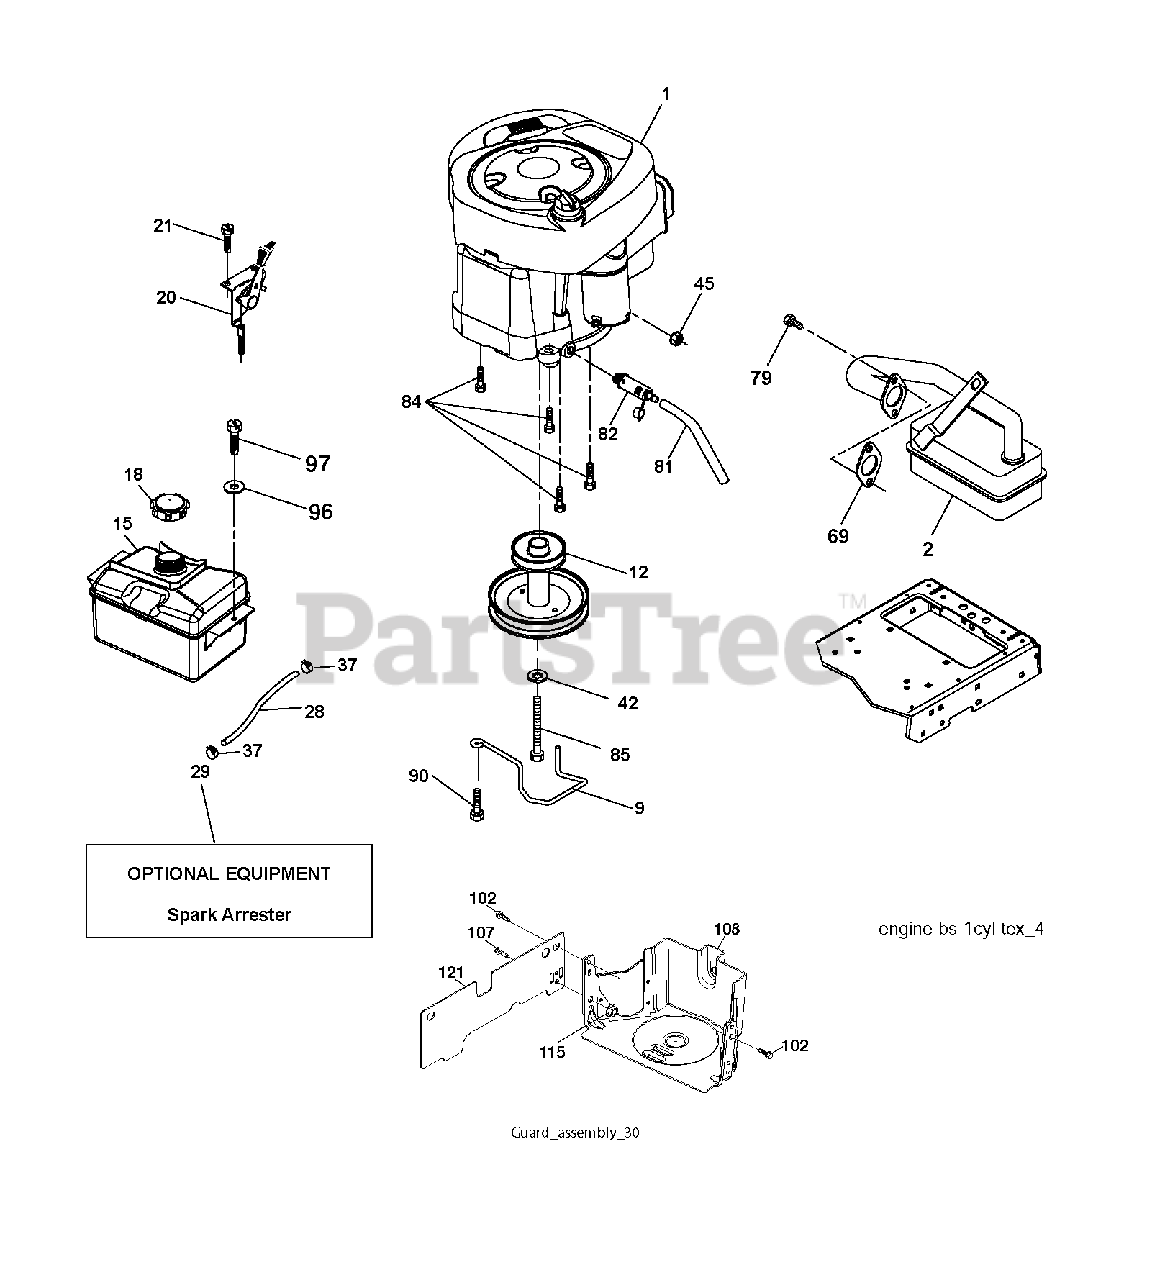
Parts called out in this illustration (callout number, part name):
9	KEEPER.BELT.ENGINE.3.25
12	PULLEY ENGINE
15	TANK FUEL FRT 1.5 GAL
18	FUEL CAP
20	CONTROL.TH/CK.C.
21	SCREW.#10 X 0.750.BOS THREAD
28	LINE.FUEL.20
29	ARRESTER SPARK (OPTIONAL)
37	HOSE CLAMP
42	LOCKWASHER
45	NUT
69	REPL BY 532 27 22-93
79	SCREW.SOCKET HD.5/16-1
81	TUBE, DRAIN OIL ASM.
82	PLUG DRAIN OIL EASY
84	SCREW.3/8-16
85	BOLT HEX 7/16-20X4-1/4"
90	SCREW 3/8-16X1
97	SCREW HEXWSHR 1/4-20X3/4
102	SCREW
107	SCREW.1/4-20X5/8
115	PALNUT 1/4
